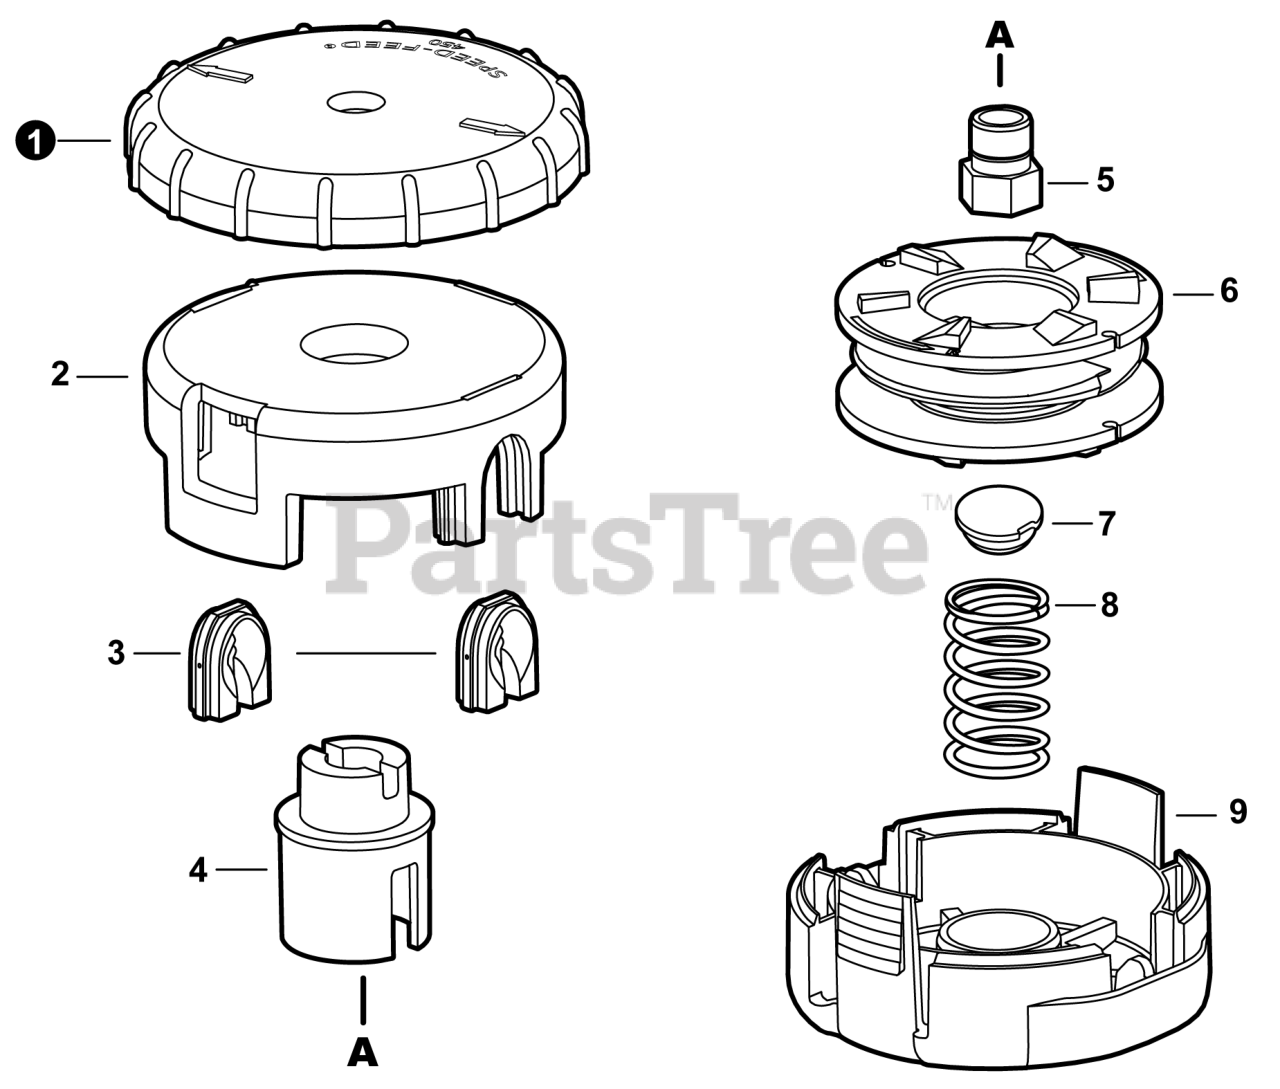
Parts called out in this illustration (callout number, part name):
2	HOUSING, SPOOL
4	HUB, SPOOL
5	BUSHING M10×1.25 LH GOLD
6	SPOOL LH
7	CAP, SPRING
8	SPRING, GOLD
9	COVER, SPOOL
